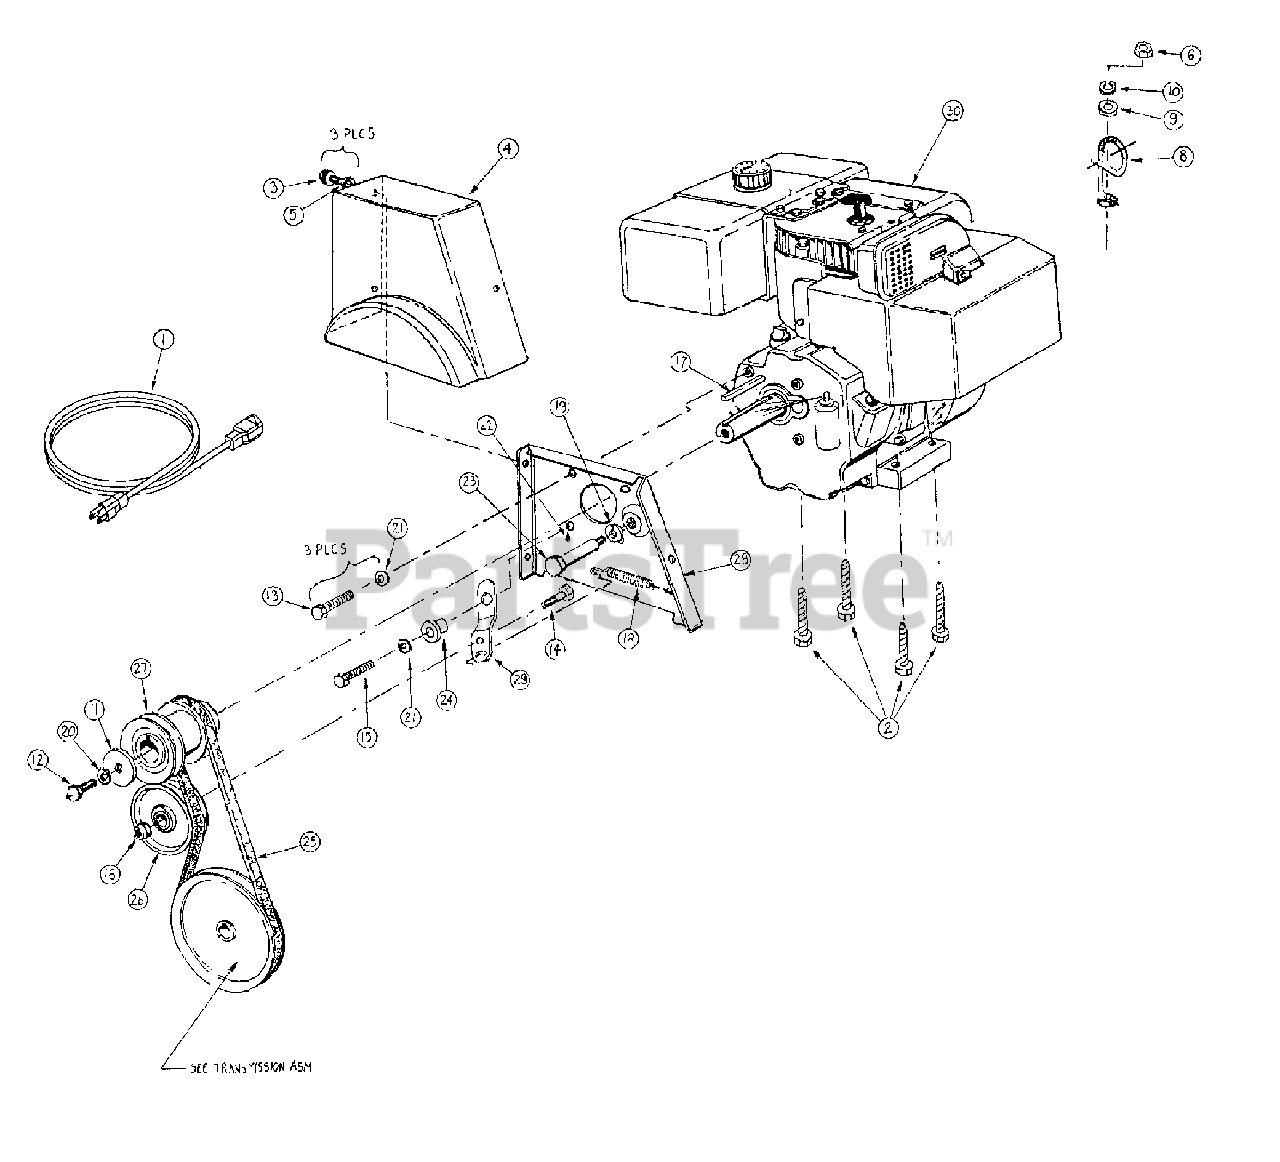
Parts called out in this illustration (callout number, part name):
1	Extension Cord 10 Ft.
2	Hex L-wash Tt Scr 3/8-16 x 1.25
3	Hwhd 5/16-18 x 1/2 Thd Roll Zn
4	Belt Cover - Pierced
5	Fl-wash .344 ID x .625 OD x .063
6	Nut 1/4-20 GR B Hex
8	Cable Control Wire
9	Fl-Wash .28 ID x .74 OD x .063
10	Lock Washer 1/4
11	Wash .39 ID x 1.75 OD x .175 T
12	Scr Hex Cap 3/8-24 x 1. Gd 8
13	Scr Hex Cap 5/16-24 x .62 Gd 5
14	Scr Hex Cap 3/8-24 x 1.5 Gd 5
15	Hhcs 5/16-24 x 7/8 Gr 5
16	Hex Ins L-nut 3/8 - 24
17	Square Key 1/4 x 1.5
18	Extension Spring .38 OD x 3.18 L
19	L-wash 3/8
20	Lock Washer 3/8 Heavy
21	Bell Wash .345 ID x .88 OD x .060
22	Grease - Sunaplex 781 - 1/10
23	Shoulder Scr .498 Dia x 3.0 Lg
24	Shldr Spcr .50 Dia x .14 Shldr
25	3v Belt 35.5 Lg
26	3.0 OD Flat Idler With Flange
27	Dbl Engine Pulley 3.25 & 2.75
30	Engine
